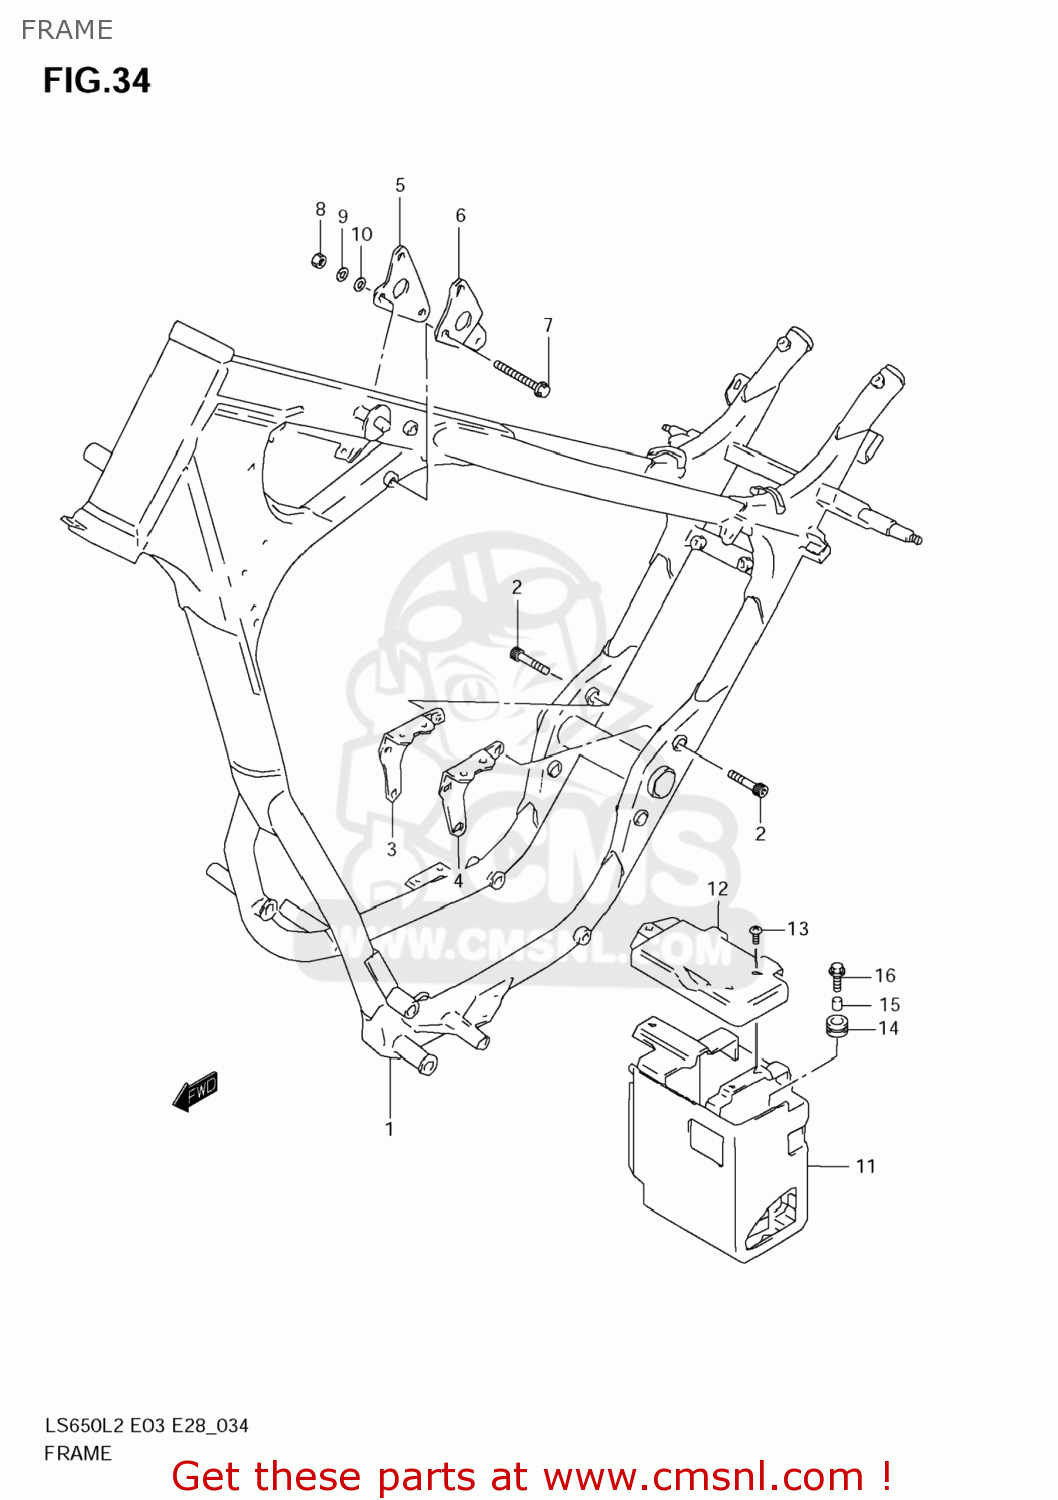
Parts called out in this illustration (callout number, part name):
1	FRAME(BLACK)
2	BOLT(8X40)
3	PLATE,ENGINE MOUNT NO.4,R
4	PLATE,ENGINE MOUNT NO.4,L
5	PLATE,ENGINE MOUNT NO.5,R
6	PLATE,ENGINE MOUNT NO.5,L
7	BOLT(8X72)
8	NUT
9	WASHER,LOCK
10	WASHER
11	HOLDER,BATTERY
12	COVER,BATTERY
13	SCREW
14	CUSHION
15	SPACER(6.5X9X7.2)
16	BOLT(6X20)
